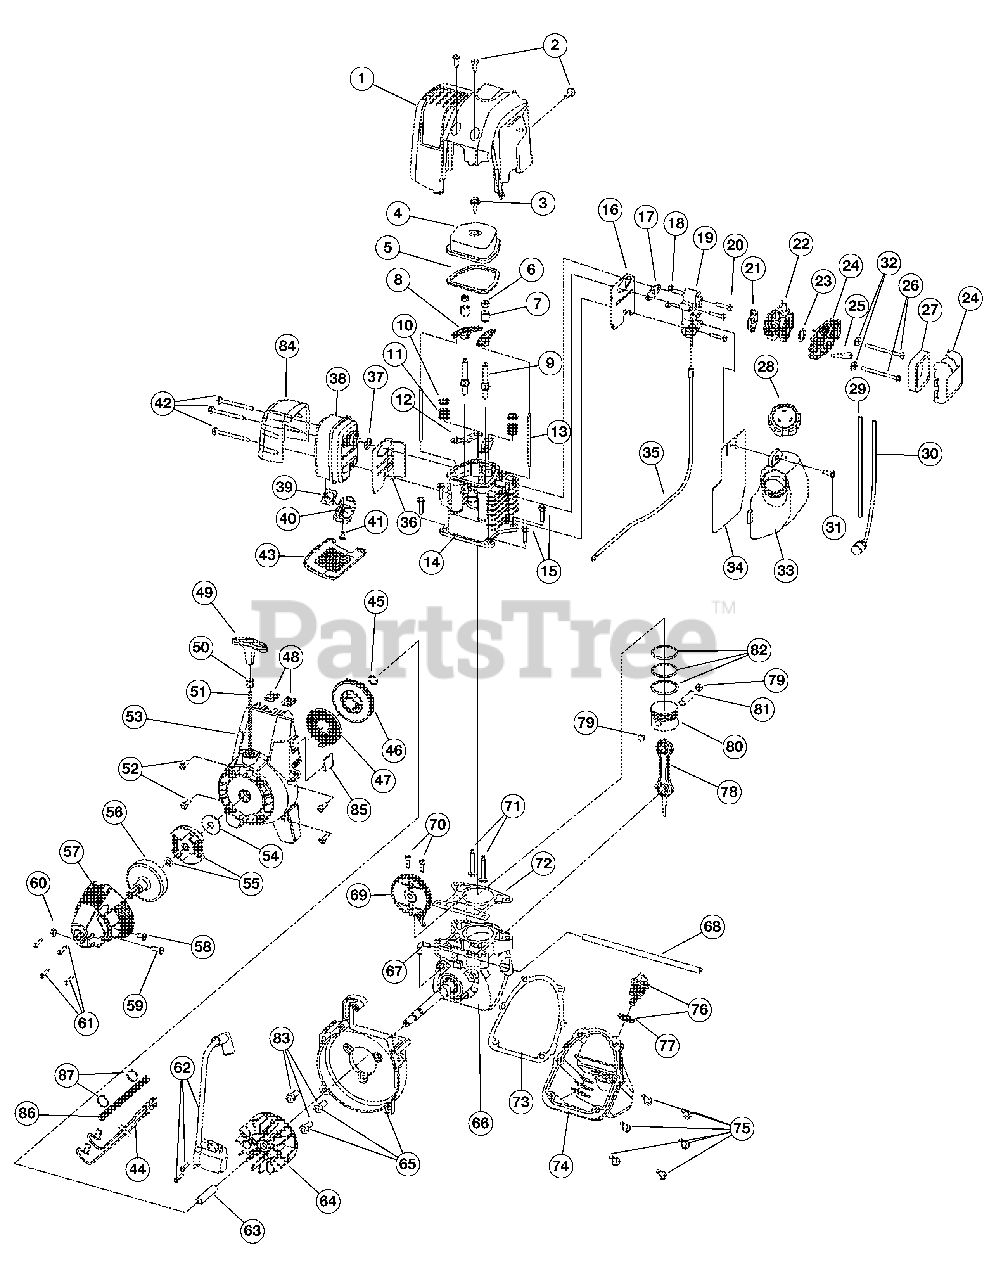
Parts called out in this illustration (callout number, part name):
1	Engine Cover
2	Engine Cover Screws
3	Valve Cover Screw
4	Valve Cover
5	Valve Cover Gasket
6	Rocker Adjustment Nut
7	Rocker Arm Pivot
9	Rocker Arm Stud
10	Valve Spring Retainer
11	Valve Spring
12	Push Rod Guide
13	Push Rod
14	Cylinder Assembly (includes 9-12, 15, 71 & 72)
15	Cylinder Screw
16	Intake Baffle
17	Carburetor Mount Gasket
18	Nut
19	Carburetor Mount (includes 18)
20	Carburetor Mount Screw
21	Carburetor Gasket
22	Carburetor with Primer
23	O-Ring, Carburetor
24	Air Filter Assembly (includes 27)
25	Breather Tube
26	Air Filter Mounting Screw
29	Fuel Return Line
30	Fuel Pick-Up Line with Filter
31	Screw
33	Fuel Tank Assembly (includes 28-30)
34	Fuel Tank Shield
35	Throttle Cable
36	Muffler Baffle
37	Muffler Gasket
38	Muffler (includes 37, 39-41)
39	Spark Arrestor Screen
40	Screen Cover
42	Muffler Mounting Screw
43	Muffler Cover
44	Switch Wire Assembly
45	Pulley Retainer
46	Recoil Pulley
47	Recoil Spring
49	Pull Handle
52	Starter Housing Screw
53	Starter Housing Assembly (includes 45-52)
54	Clutch Washer
55	Clutch with Spacer
56	Clutch Drum
57	Clutch Cover
58	Anti-Rotation Screw
59	Screw
61	Clutch Cover Screw
62	Ignition Module Assembly
64	Flywheel
65	Shroud Assembly (includes 83)
66	Crankcase Assembly (includes 67 & 68)
67	Breather Fitting
68	Breather Hose
69	Cam Bracket Assembly (includes 70)
70	Cam Bracket Screw
71	Valves, Intake and Exhaust
72	Cylinder Gasket
73	Oil Pan Gasket
74	Oil Pan (includes 73 & 75)
75	Oil Pan Screw
76	Dipstick Assembly (includes 77)
78	Connecting Rod
79	Wrist Pin Button
80	Piston (includes 82)
82	Piston Ring Set
83	Shroud Screw
84	Heat Shield
86	Wire Cover
87	Cable Clamp
